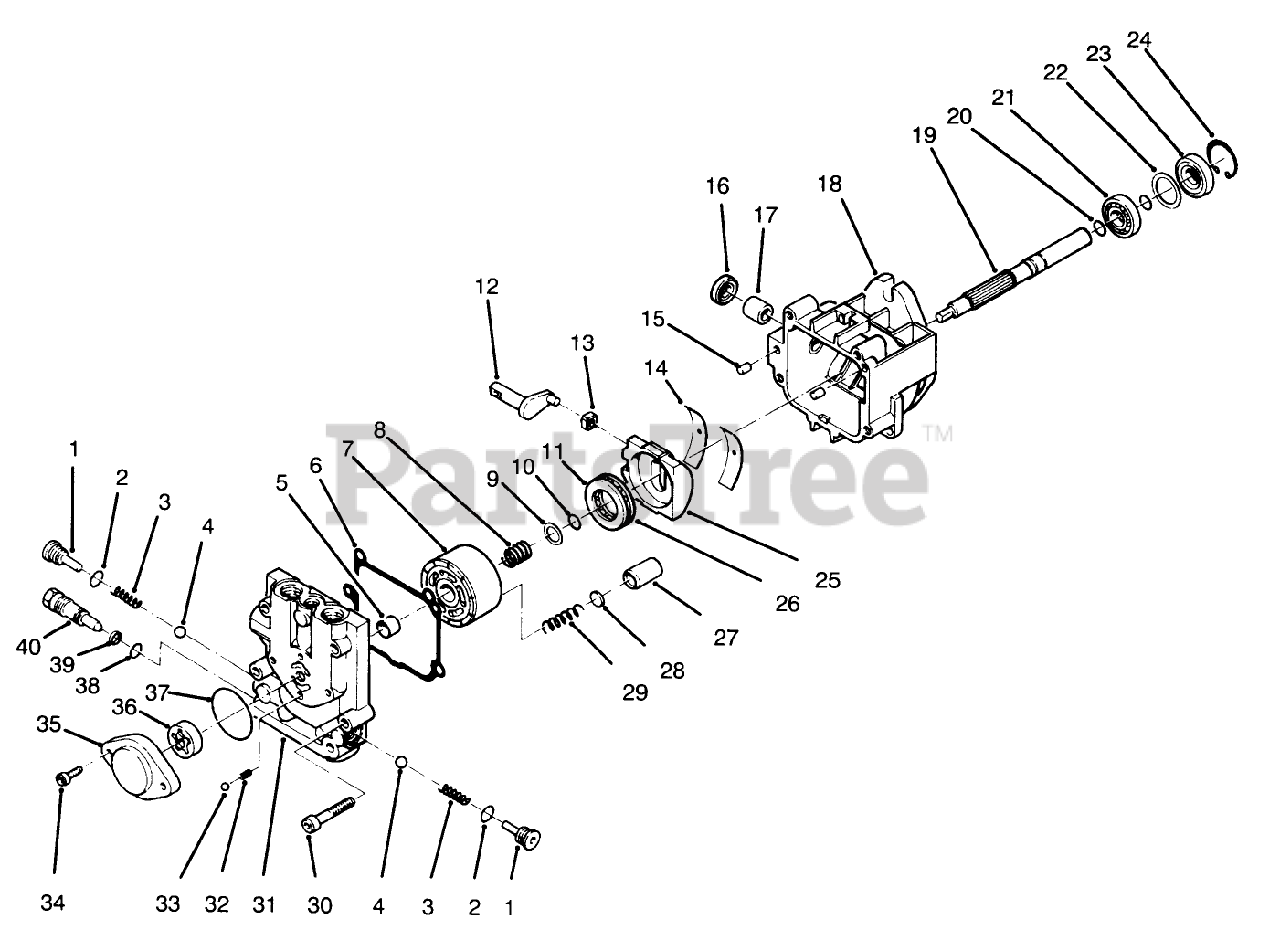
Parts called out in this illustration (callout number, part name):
1	Check Valve Kit (Incl. Ref. #2-4)
2	Seal-O-Ring
4	Ball
5	Journal-Bearing
6	Gasket-End Cap
9	Washer
11	Plate-Thrust
12	Arm-Trunnion
13	Guide-Slot
14	Cradle-Bearing
16	Seal-Lip
17	Journal-Bearing
19	Shaft
21	Bearing-Ball
23	Seal-Lip
25	Swashplate Assembly
26	Roller-Thrust
29	Spring-Piston
32	Ball
35	Housing-Charge Pump
36	Gerotor Assembly
37	Seal-O-Ring
38	Seal-O-Ring
39	Ring-Back-Up
40	Valve-Bypass
